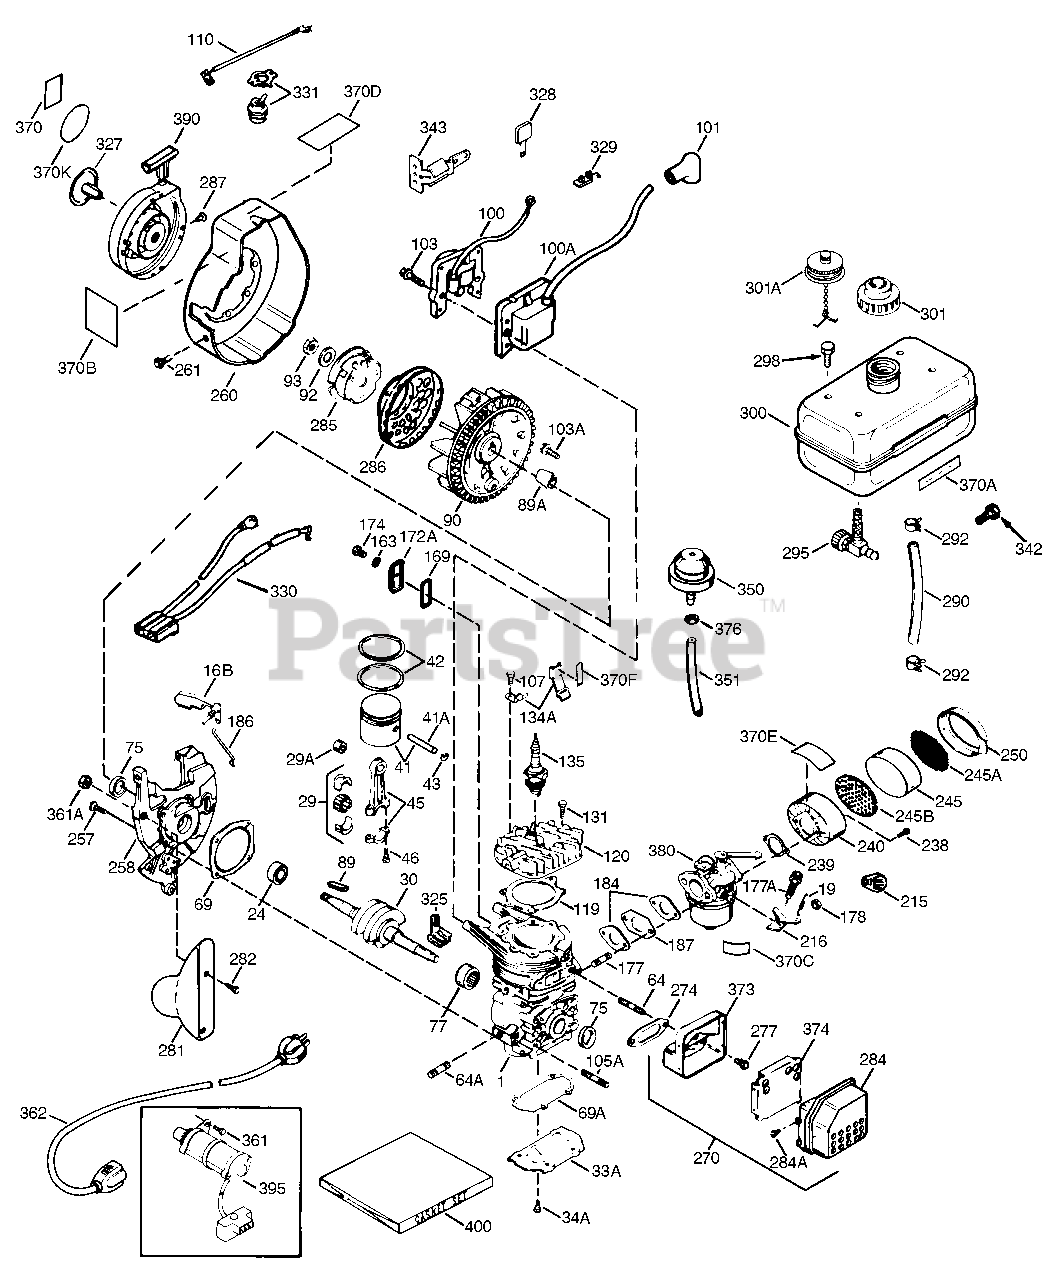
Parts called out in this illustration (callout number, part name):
1	"Cylinder Order S/B if replacement isn eeded
16B	Air Vane
19	Extension Spring
24	Ball Bearing
29	Needle Bearing & Liner Set 37 Needles
29A	Cartridge Bearing
30	Crankshaft
33A	Cover Plate
41	Piston & Pin Ass'y. (Incl. 43)
42	Ring Set
43	Piston Pin Retaining Ring
45	Connecting Rod Ass'y. Incl. 29, 29A,& 46
46	Connecting Rod Bolt
69	* Cylinder Cover Gasket
69A	* Cover Plate Gasket
75	Oil Seal
77	Cartridge Bearing
89A	Adapter Sleeve
90	Flywheel
92	Belleville Washer
93	Flywheel Nut
100	Solid State Ignition (Incl. 101)
101	Spark Plug Cover
103	Screw, Torx T-15, 10-24 x 15/16"
119	* Cylinder Head Gasket
120	Cylinder Head
130B	Screw, 1/4-20 x 1/2"
135	Resistor Spark Plug (RCJ8Y)
169	* Compression Release Cover Gasket
172A	Compression Release Cover
177	Screw, 5/32 Allen, 1/4-20 x 1"
184	* Carburetor Gasket
186	Governor Link
209	Screw, Torx T-25, 10-24 x 1/2"
211	Screw, Torx T-25, 10-32 x 5/8"
216	R.P.M. Adjusting Lever
239	Air Cleaner Gasket
257	Screw, Torx T-30, 1/4-20 x 5/8"
258	Blower Housing Base (Incl. 75)
260	Blower Housing
274	* Exhaust Gasket
285	Starter Cup
287	Screw, 8-32 x 21/64"
325	Wire Clip
330	Wire Harness
353A	Screw, Torx T-30, 1/4-20 x 3/4"
361	Screw, Torx T-30, 1/4-20 x 7/8" Optio nal
380	Carburetor (Incl. 184)
390	Rewind Starter
395	Electric Starter Motor (120 Volt) Opt ional
400	* Gasket Set (Incl. items marked PK in notes) Incl. (1) each of part #'s510 207A, 510274A, 510292A, 510323A,51032 5A, 510326A, 510346A, and (2) ofpart # 510110A
900	Replacement Short Block 710569, order from 71-999
900	Replacement Engine None
